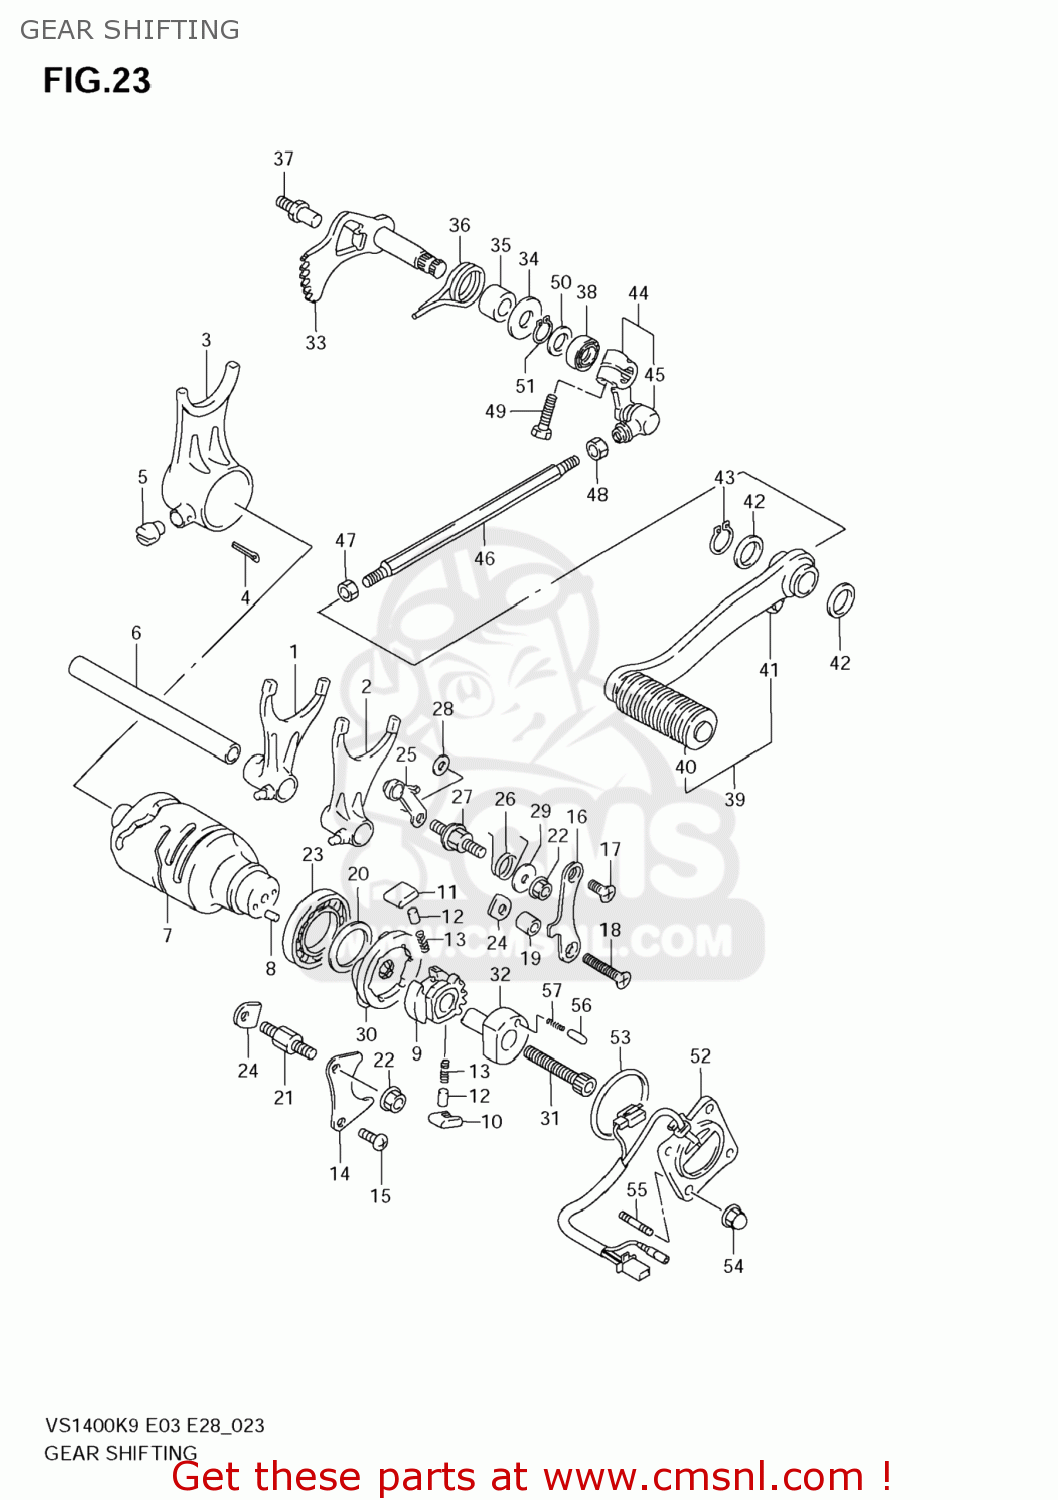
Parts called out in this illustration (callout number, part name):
1	FORK,GEAR SHIFT NO.1
2	FORK,GEAR SHIFT NO.2
3	FORK,GEAR SHIFT NO.3
4	PIN
5	PIN
6	SHAFT,GEAR SHIFT FORK(L:152)
7	CAM,GEAR SHIFT
8	PIN
9	GEAR,GEAR SHIFT CAM DRIVEN
10	PAWL,GEAR SHIFT NO.1
11	PAWL,GEAR SHIFT NO.2
12	PIN(5X8)
13	SPRING
14	LIFTER,GEAR SHIFT POLE
15	BOLT(6X12)
16	GUIDE,GEAR SHIFT CAM
17	SCREW(6X12)
18	SCREW(6X30)
19	SPACER(6.5X10X14)
20	WASHER(25X32X3)
21	BOSS,SHIFT POLE LIFTER
22	NUT
23	BEARING(25X47X8)
24	RETAINER
25	STOPPER,GEAR SHIFT CAM
26	SPRING
27	SUPPORT,CAM STOPPER ARM
28	WASHER
29	WASHER(6.5X18X2)
30	PLATE,GEAR SHIFT CAM
31	BOLT(6X50)
32	HOLDER,NEUTRAL SWITCH
33	SHAFT,GEAR SHIFT
34	WASHER(12.5X28X1.2)
35	SPACER(12X20X15.3)
36	SPRING
37	STOPPER,SHIFT ARM
38	OIL SEAL
39	LEVER ASSY,GEAR SHIFT
40	RUBBER,GEAR SHIFT PEDAL
41	COVER,DUST
42	WASHER(14.5X22X1)
43	CIRCLIP
44	ARM,GEAR SHIFT LINK
45	COVER,DUST
46	ROD,GEAR SHIFT LINK
47	NUT
48	NUT
49	BOLT
50	SHIM(12X20X1)
51	CIRCLIP
52	BASE ASSY,NEUTRAL SW TERMINAL
53	O RING(D:2.4,ID:35.5)
54	NUT
55	BOLT,STUD
56	PIN
57	SPRING
